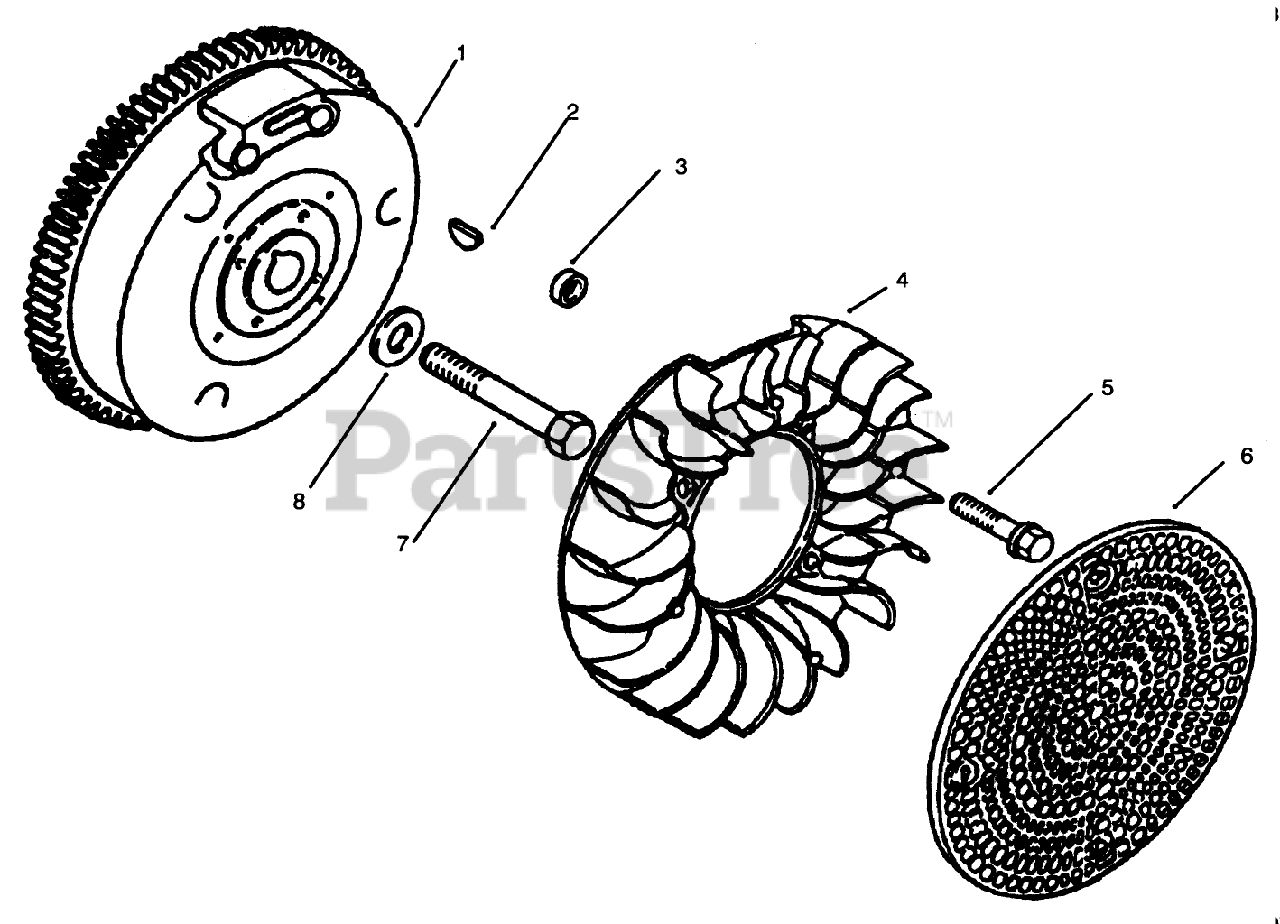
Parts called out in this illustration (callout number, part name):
1	Flywheel
2	Key-Woodruff
3	Spacer
4	Fan
5	Screw-Hex Hd
6	Screen
7	Screw
8	Washer
